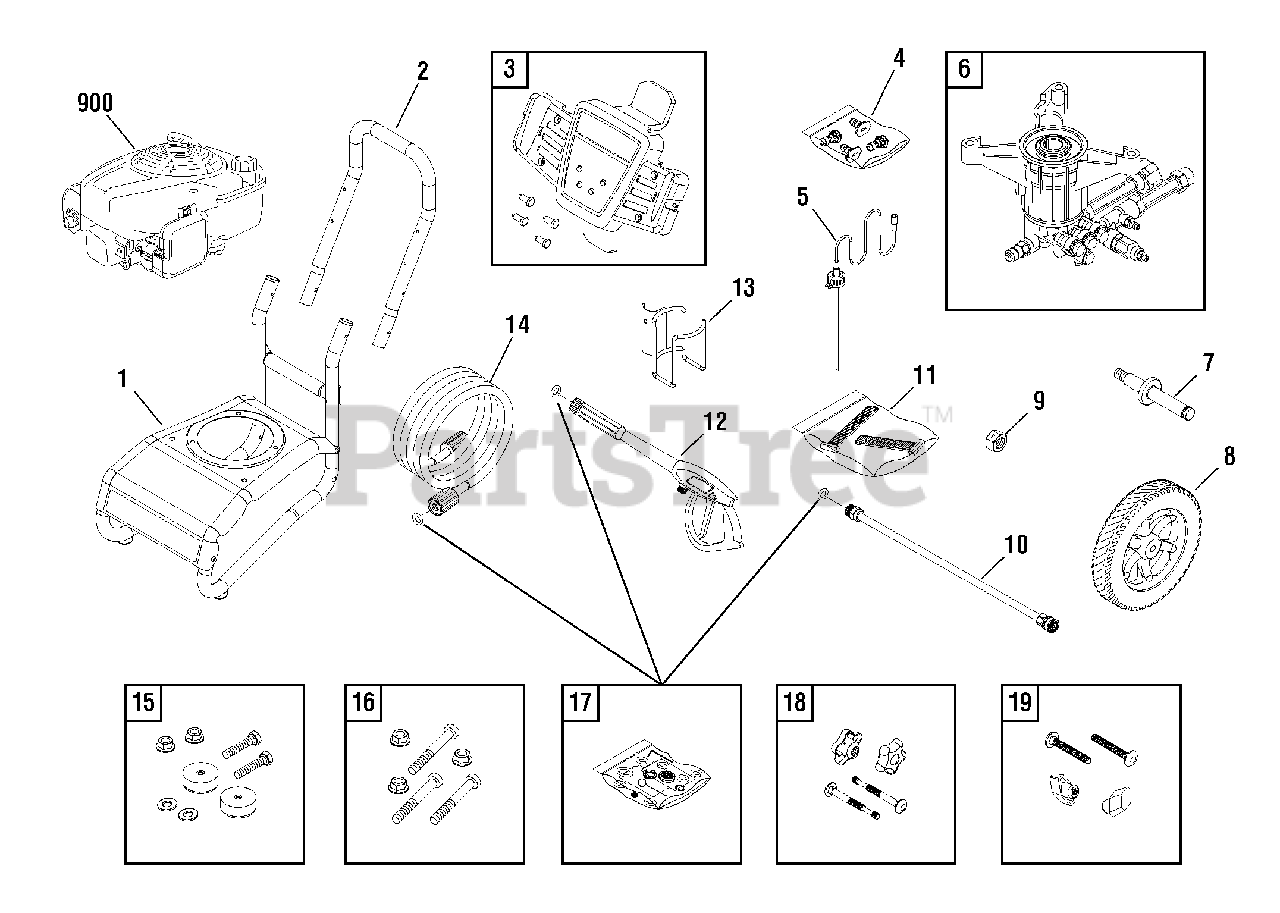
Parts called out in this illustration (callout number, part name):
6	PUMP
12	GUN
14	HOSE
15	MOUNT-VIBRATION
16	KIT-HARDWARE PUMP
900	** ENGINE
